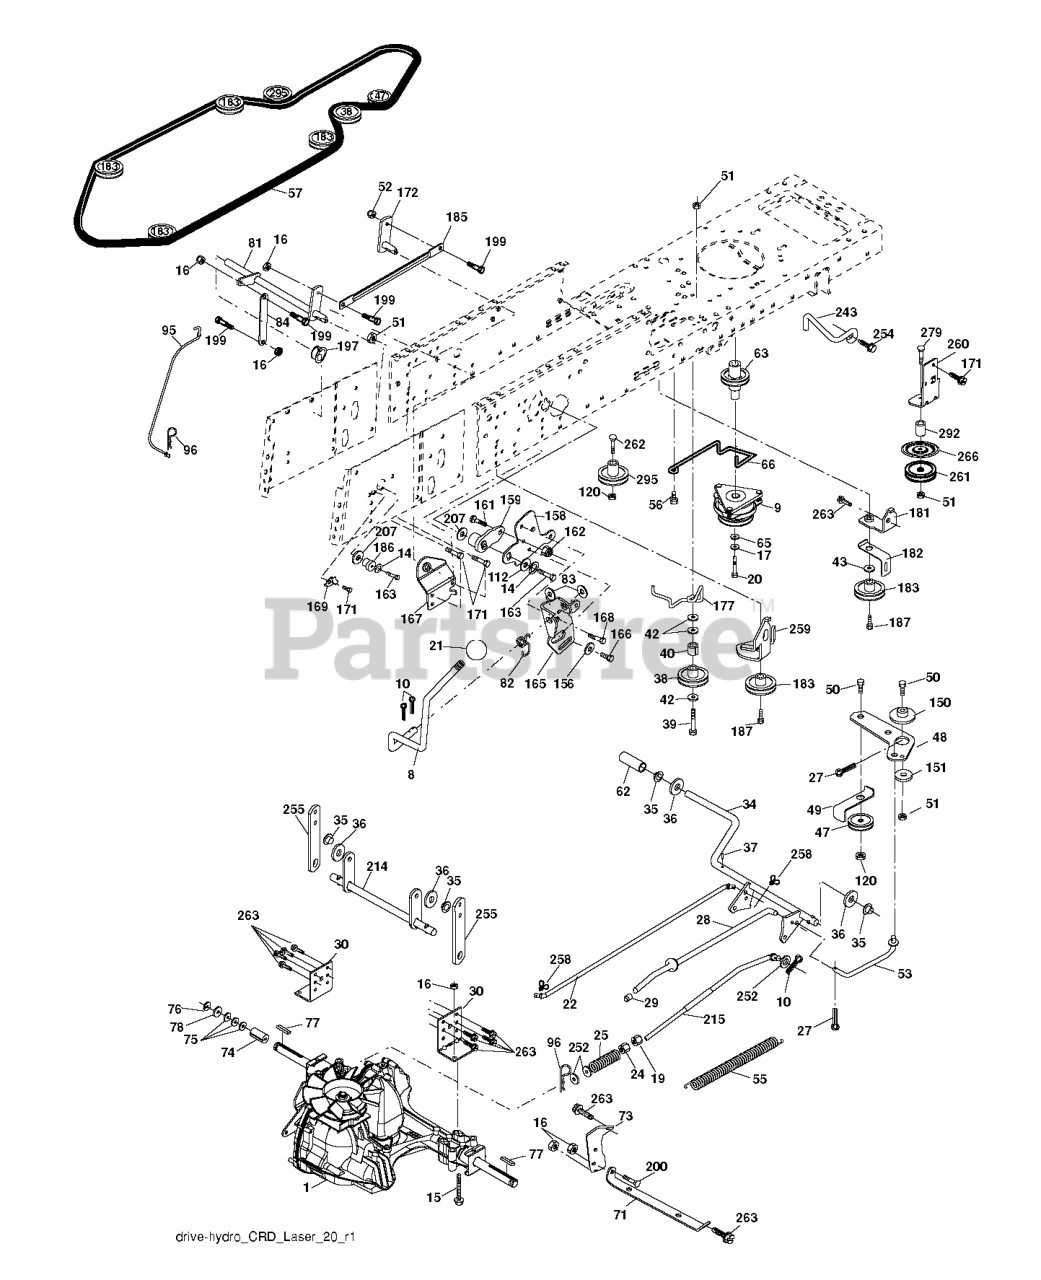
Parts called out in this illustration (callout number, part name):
8	ROD SHIFT FENDER ADJUST LT
9	CLUTCH.ELECTRIC.OGURA.EURO.
10	PIN COTTER
14	LOCKWASHER
15	BOLT HEX 5/16-18 GR 5
16	NUT.71038.31-18.HEX.NYLOCK
19	NUT
20	BOLT HEX 7/16-20X4-1/4"
21	KNOB.DUCKHEAD.1/2
22	ROD
24	NUT
25	SPRING BRAKE ROD
27	COTTER PIN
28	ROD, PARKING BRAKE
29	PLUNGER CAP
30	BRKT, TRNSXLE MNT 20"
34	SHAFT, FOOT PEDAL
35	BEARING.NYLON
37	DRIVE PIN
38	PULLEY.FLAT
42	WASHER
47	IDLER PULLEY
48	BELLCRANK, CLUTCH
49	RETAIN BELT
50	BOLT.3/8-16X1.50
52	LOCKNUT
53	LINK.CLUTCH.7.66.2005
55	SPRING, RETURN LT
56	SCREW.3/8-16
57	V-BELT 113"
62	PEDAL COVER T
63	PULLEY.ENGINE.CVX.LT
65	LOCKWASHER
66	KEEPER BELT ENGINE
71	STRAP TORQUE LH HYDRO
73	STRAP TORQUE RH HYDRO
74	SPACER AXLE
77	SQUARE KEY
81	ASM.CROSS.SHAFT.REAR.CRD.0510
82	SHIFT SPRING
83	WASHER
84	LINK.PNT.TRANSAXLE.0510.CRD
95	LINK
96	RETAINER M
120	NUT LOCK FLG 3/8-16 UNC
150	BUSHING.BELLCRANK.GRD.DR
151	WASHER 12/32X2X10GA
156	WASHER.SRRTD.5/16
158	BRACKET
159	RB HUB.SHIFT
161	BOLT
162	NUT.CROWNLOCK.1/4
165	RP BRACKET
166	CAPSCREW.HXHD.FLG.5/16-18X.625
167	BRACKET.SUPT.SHIFT.CRD
168	BOLT.SHOULDER.5/16-18X
169	PLATE.FASTENING.CROSS.SHAFT
172	LINK
181	BRACKET
182	BELT GUIDE
183	PULLEY.V-IDLER.GRND.DR
185	LINK
186	HUB.TAPERED.ROUND.CRD
187	BOLT.5/16-18X1.25
197	NYLINER SNAP 5/8" ID
199	BOLT SHOULDER 5/16-18 UNC
207	WASHER NYL
214	LEVER
215	ROD
243	BRACKET, ANTI-ROTATION
252	WASHER
254	SCREW 3/8-16X1
255	SHAFT
258	CLIP RETAINER
259	BRACKET
261	FLAT IDLER PULLEY
263	SCREW, 3/8-16X3/4
266	PROTECTOR
292	SPACER
295	PULLEY IDLER COMPOSITE
